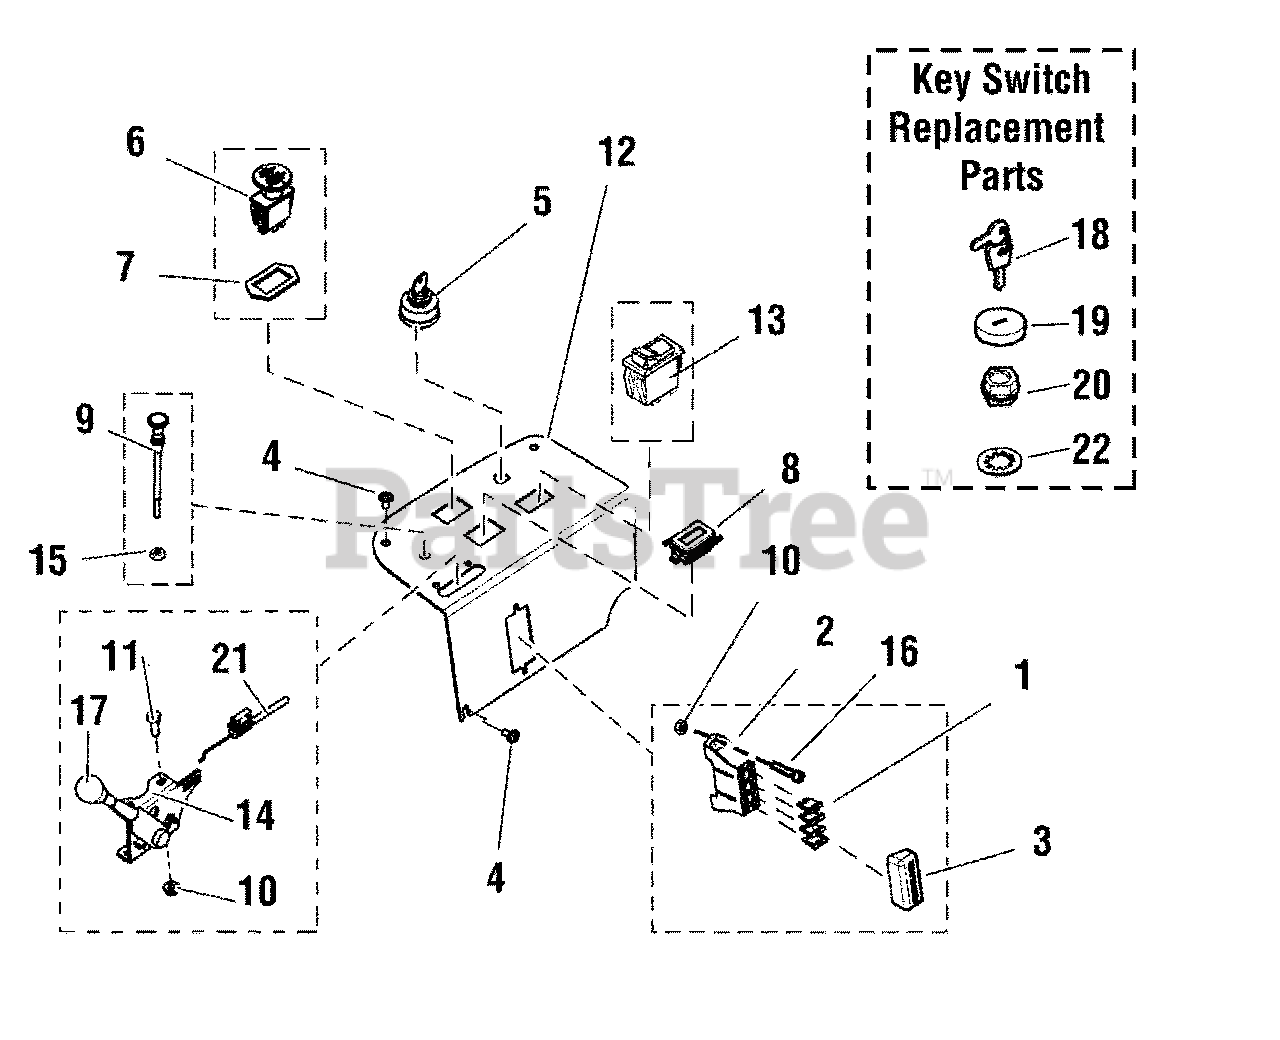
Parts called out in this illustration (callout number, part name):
1	FUSE, ATO, 20 AMP
2	FUSE BLOCK
3	COVER, VINYL FUSE BLOCK
4	SCREW, 1/4-20 X 1/2 ALLEN BH
5	SWITCH ASMY-IGNITION INDAK NO KEYS
6	SWITCH, BLADE ENGAGEMENT
7	RING, SWITCH RETAINER
8	HOUR METER W/ SUPRESSOR
9	CABLE, CHOKE CONTROL, 51" (Z)
10	NUT, #10-24 HEX NYLON LOCK
11	SCREW, #10-24 X 3/4 ROUND PHILLIPS
12	PLATE, CONTROL PANEL, COBALT - BLACK
13	SWITCH HEADLIGHT
14	LEVER, THROTTLE CONTROL
15	NUT, 3/8-24 HEX (SV)
16	SCREW, #10-24 X 2 ROUND PHILLIPS
17	THROTTLE CONTROL HANDLE/KNOB
18	KEYS. BLISTER PK KIDS+MWRS DON'T MIX
19	COVER, SWITCH (SV)
20	NUT-HEX FLANGE 5/8-32 IGN SW DIE CAST (SV)
21	CABLE, THROTTLE 47"
22	LOCKWASHER-INTERNAL TOOTH, .625 THIN BLK (SV)
